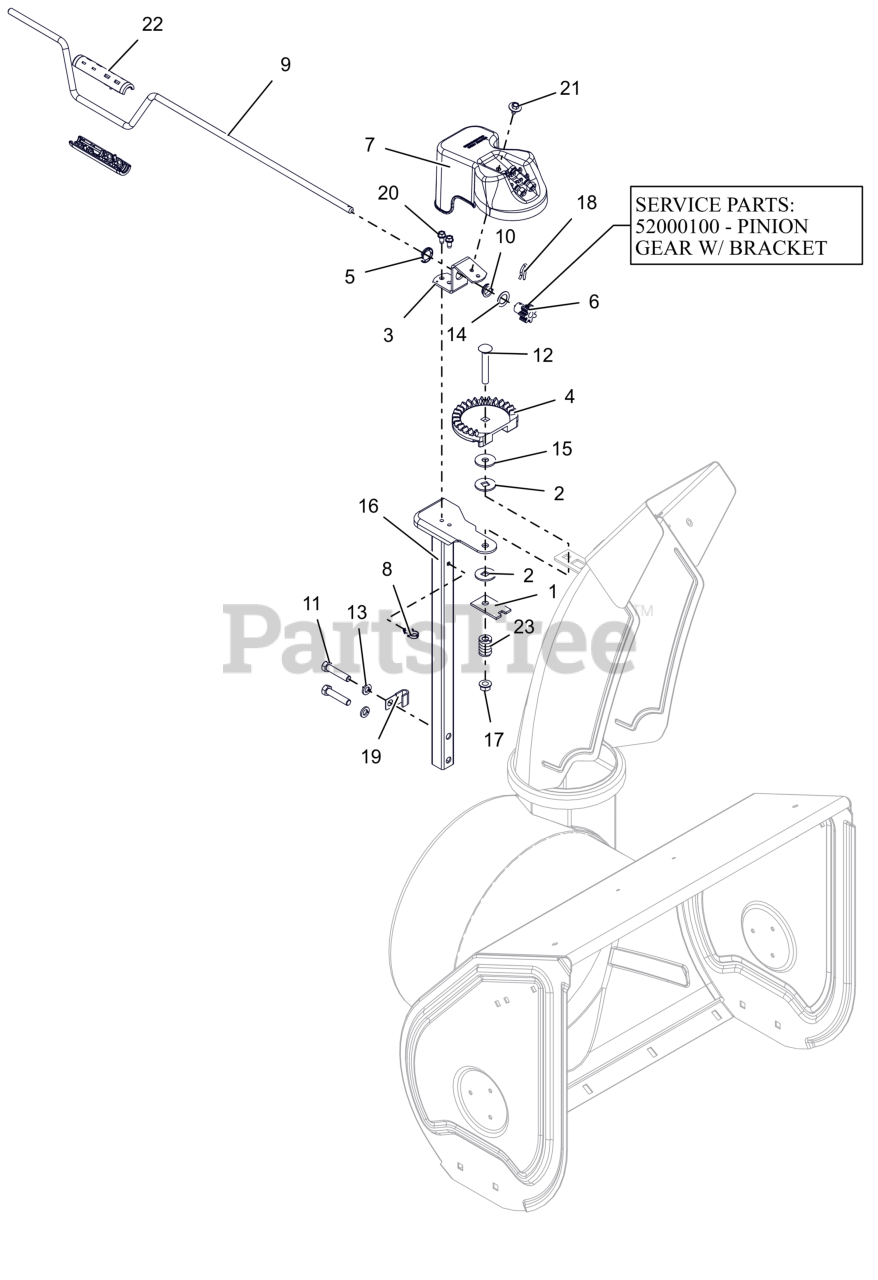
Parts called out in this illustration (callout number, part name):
1	PLATE, FRICTION
2	FRICTION WASHER
3	BRACKET, PINION GEAR
4	CHUTE GEAR
5	PUSHNUT .625
6	PINION GEAR - CHUTE
6	PINION GEAR W/BRACKET
7	GEAR COVER ASSY LG SHEAR BOLT
8	CLIP, CABLE GUIDE
9	ROD, CHUTE CRANK
10	BUSHING, POLYLINER-.63 SNAPIN
11	BLT, HEX .38-16X1.75 G5 ZCC
12	BLT,RHSN .38-16X2.50 G5 ZCC
13	WSHR,LK-REG .375X.094 ZCC
14	WSHR-THRST .625 X 1.0 X .03
15	WSHR FL STL .406X1.25X.10ZC120
16	PEDESTAL, CHUTE - CRANK
17	NUT-LK-TOP-FLG .38-16 ZC120
18	PIN, SPRING CLIP
19	J-CLAMP
20	SCR-TAP .25-20X.50 HWH ZCC
21	SCR, TAP .25-20X.50 LG HWH ZCC
22	KNOB,CHUTE CRANK-DELUXE
23	SG-COMP .187X.56X1.62
